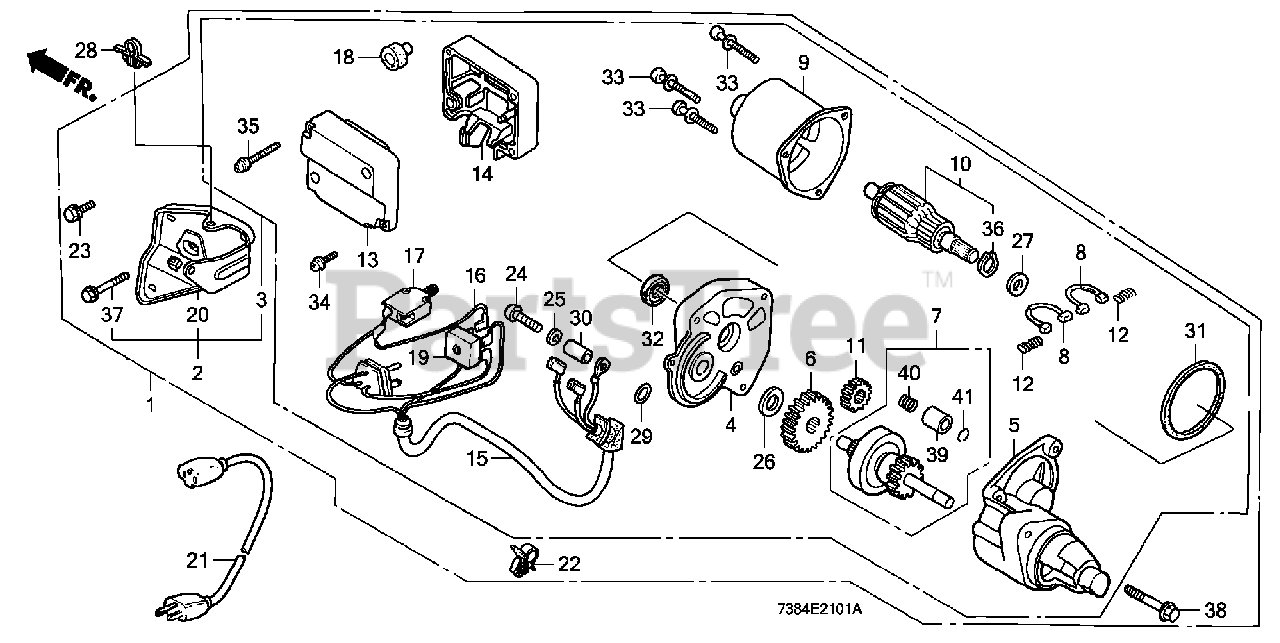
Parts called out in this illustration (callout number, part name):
1	STARTER KIT, SELF (A.C.) Use from Engine SN 1171449.
2	MOTOR ASSY., STARTER Use from Engine SN 1171449.
3	MOTOR ASSY., STARTER (A.C.) Use from Engine SN 1171449.
4	HOUSING, CENTER Use from Engine SN 1171449.
5	HOUSING, PINION Use from Engine SN 1171449.
6	GEAR, REDUCTION Use from Engine SN 1171449.
7	CLUTCH Use from Engine SN 1171449.
8	BRUSH Use from Engine SN 1171449.
9	YOKE Use from Engine SN 1171449.
10	ARMATURE Use from Engine SN 1171449.
11	GEAR, DRIVE Use from Engine SN 1171449.
12	SPRING, BRUSH RETURN Use from Engine SN 1171449.
13	COVER Use from Engine SN 1171449.
14	CASE Use from Engine SN 1171449.
15	WIRE Use from Engine SN 1171449.
16	SUB-WIRE Use from Engine SN 1171449.
17	SWITCH, STARTER Use from Engine SN 1171449.
18	CAP Use from Engine SN 1171449.
19	DIODE Use from Engine SN 1171449.
20	BRACKET, SWITCH BOX Use from Engine SN 1171449.
21	WIRE, POWER Use from Engine SN 1171449.
22	HOLDER, STOP SWITCH WIRE Use from Engine SN 1171449.
23	BOLT, FLANGE (6X12) (CT200) Use from Engine SN 1171449.
24	SCREW, TRUSS (4X30) Use from Engine SN 1171449.
25	WASHER, STAR (4MM) Use from Engine SN 1171449.
26	WASHER (A) Use from Engine SN 1171449.
27	WASHER (B) Use from Engine SN 1171449.
29	O-RING Use from Engine SN 1171449.
30	COLLAR Use from Engine SN 1171449.
31	GASKET Use from Engine SN 1171449.
32	OIL SEAL Use from Engine SN 1171449.
33	SCREW-WASHER (5X30) Use from Engine SN 1171449.
34	SCREW-WASHER (4X20) Use from Engine SN 1171449.
35	SCREW-WASHER (4X30) Use from Engine SN 1171449.
36	CIRCLIP (OUTER) (12MM) Use from Engine SN 1171449.
37	BOLT, FLANGE (6X40) Use from Engine SN 1171449.
38	BOLT, FLANGE (8X35) Use from Engine SN 1171449.
39	STOPPER, PINION Use from Engine SN 1171449.
40	SPRING, COIL Use from Engine SN 1171449.
41	RING, RETAINING Use from Engine SN 1171449.
